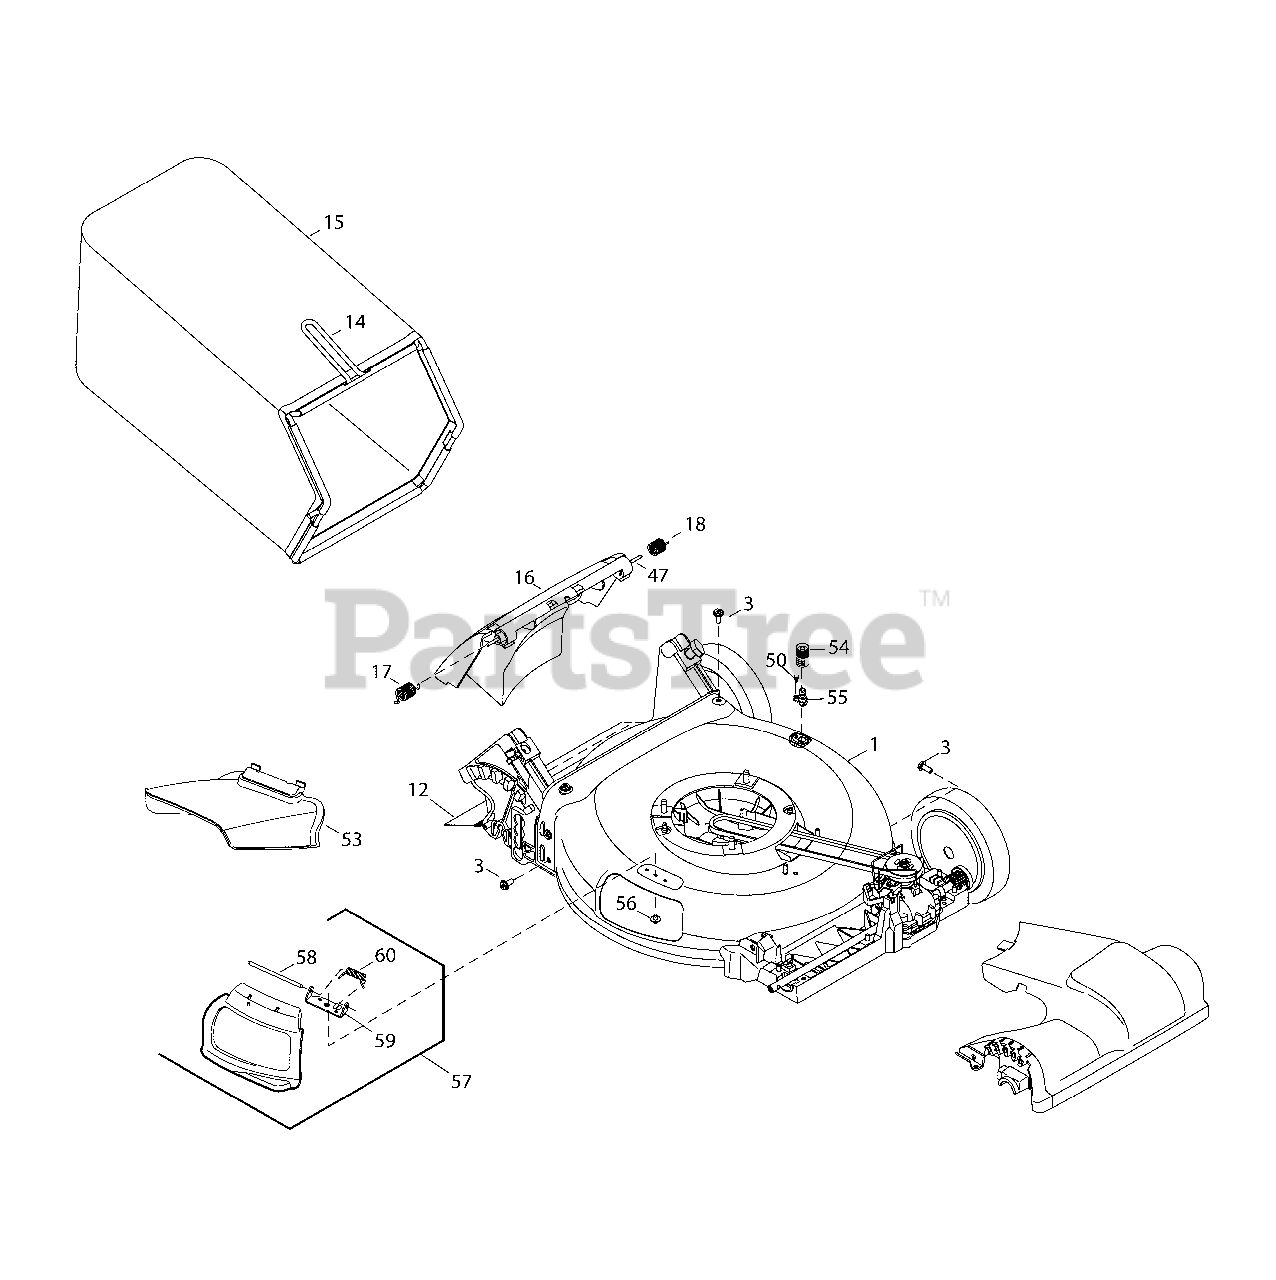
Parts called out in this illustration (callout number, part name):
3	SCREW, 5/16-14 x 3/4
12	SHIELD, Trailing
14	FRAME, Grass Bag
15	BAG, Grass
16	DOOR, Rear Discharge
17	SPRING, Torsion, RH
18	SPRING, Torsion, LH
47	ROD, Pivot
50	BOLT, Shoulder, 1/4-20 x 1/2
53	CHUTE, Side Discharge
54	ADAPTER, Water Nozzle
55	NOZZLE, Water
56	SCREW, 1/4-20 x 1/2
57	MULCH PLUG
58	PIN, Hinge
59	BRACKET, Chute Deflector
60	SPRING, Torsion
